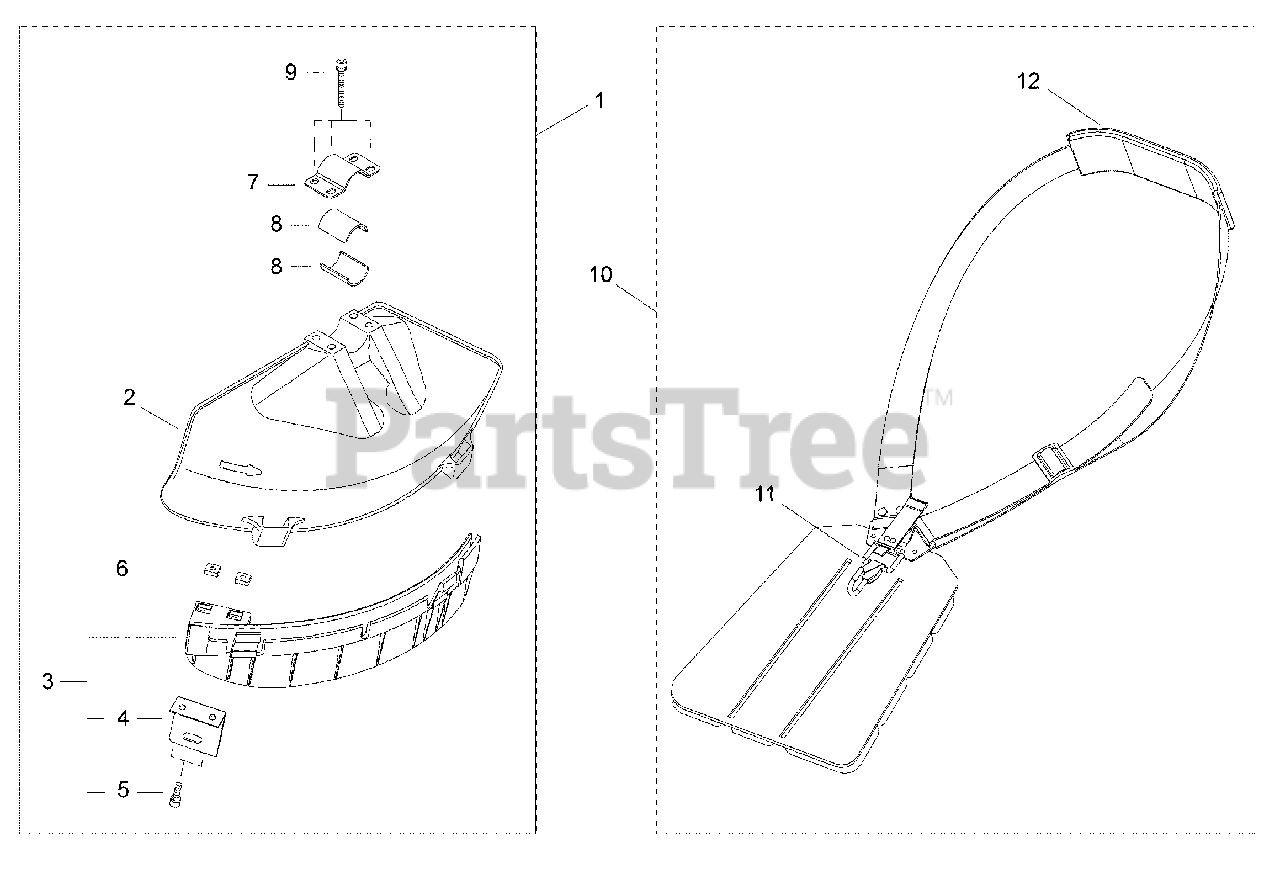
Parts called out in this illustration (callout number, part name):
1	DEBRIS SHIELD KIT
2	SHIELD, DEBRIS PLASTIC
3	DEBRIS SHIELD EXTENSION ASSY
4	CUTTER
5	BOLT M5×16
6	NUT M5
7	CLAMP, UPPER
8	SPACER 26
9	BOLT M5×45
10	HARNESS ASSY, BRUSHCUTTER
11	HOOK, SNAP
12	PAD, SHOULDER
